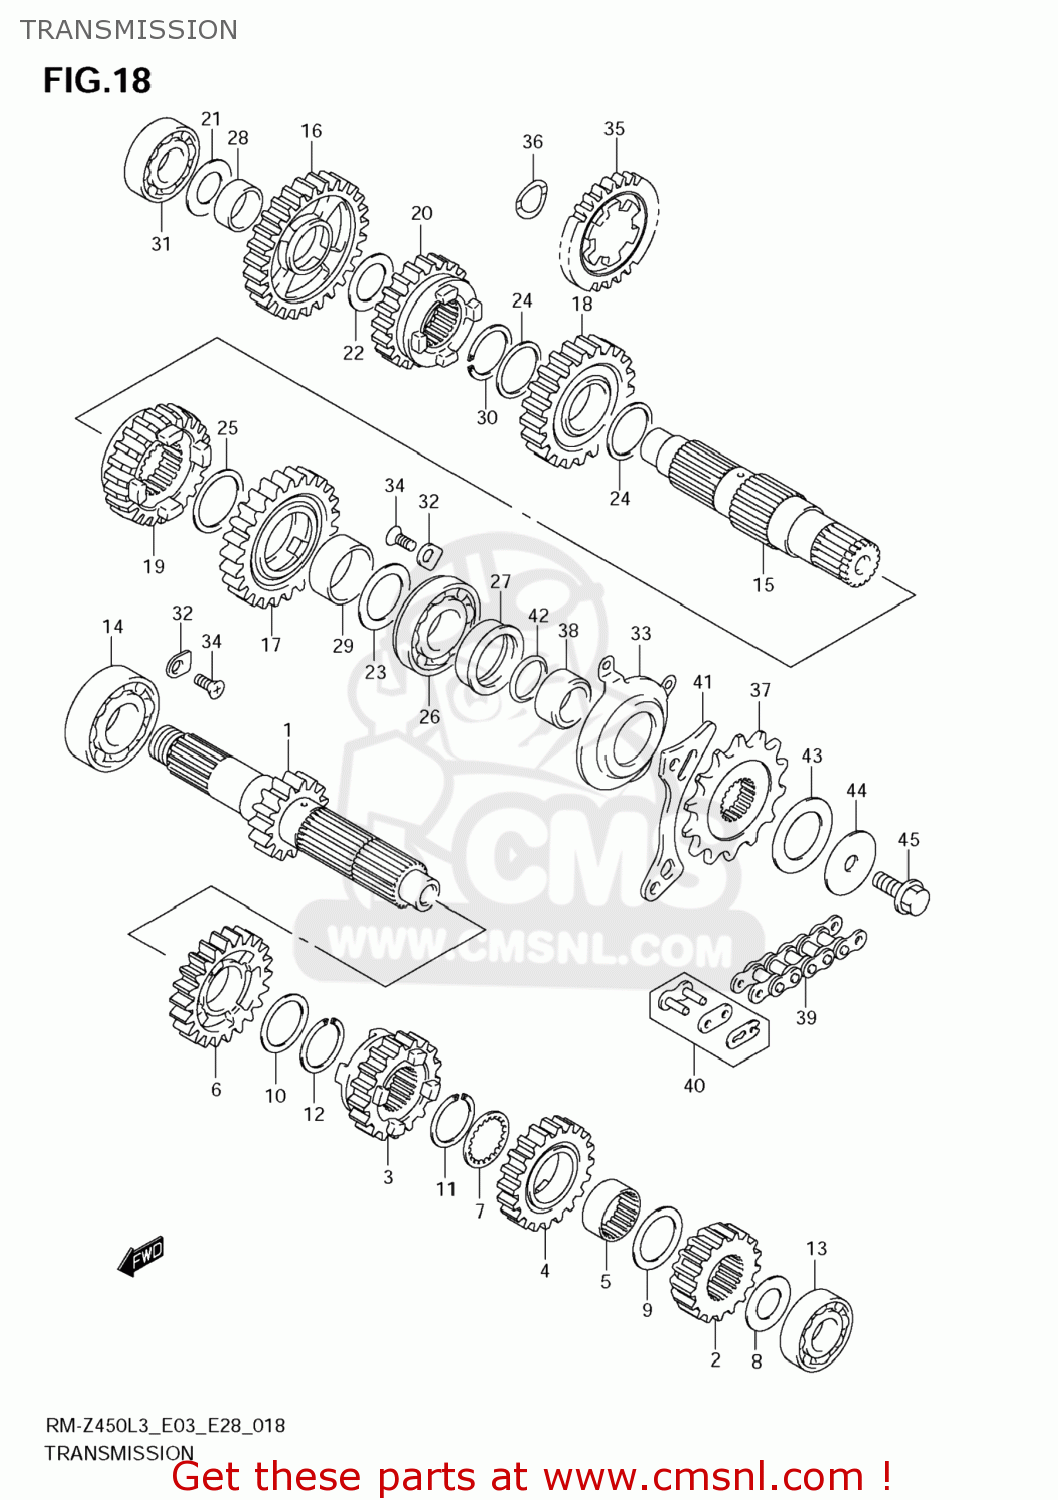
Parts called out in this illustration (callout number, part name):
1	SHAFT,COUNTER
2	GEAR,2ND DRIVE
3	GEAR,3RD DRIVE
4	GEAR,4TH DRIVE
5	BUSH,4TH DRIVE GEAR
6	GEAR,5TH DRIVE
7	WASHER,LOCK
8	SHIM(17X30X1)
9	SHIM(25X34X1)
10	SHIM(25X32X1)
11	CIRCLIP
12	CIRCLIP
13	BEARING
14	BEARING
15	SHAFT,DRIVE
16	GEAR,1ST DRIVEN
17	GEAR,2ND DRIVEN
18	GEAR,3RD DRIVEN
19	GEAR,4TH DRIVEN
20	GEAR,5TH DRIVEN
21	SHIM(17X30X1)
22	SHIM(20X30X1)
23	SHIM(24X34X1)
24	SHIM(25X30X1)
25	SHIM(27X33X1)
26	BEARING(24X56X14)
27	SEAL,OIL(31X40X6.7)
28	BUSH(20X24X10)
29	BUSH(27X31X13)
30	CIRCLIP
31	BEARING
32	RETAINER,COUNTER BEARING,R
33	RETAINER,DRIVE SHAFT OIL SEAL
34	SCREW(6X12)
35	GEAR,KICK STARTER IDLE
36	WASHER,KICK IDLE
37	SPROCKET,ENGINE(13T)
38	SPACER,ENGINE SPROCKET
39	CHAIN,DRIVE
40	JOINT SET,CHAIN
41	PLATE,FR CHAIN GUIDE
42	D RING,SPROCKET SPACER
43	WASHER,ENGINE SPROCKET WAVE
44	WASHER,ENGINE SPROCKET
45	BOLT(8X30)
